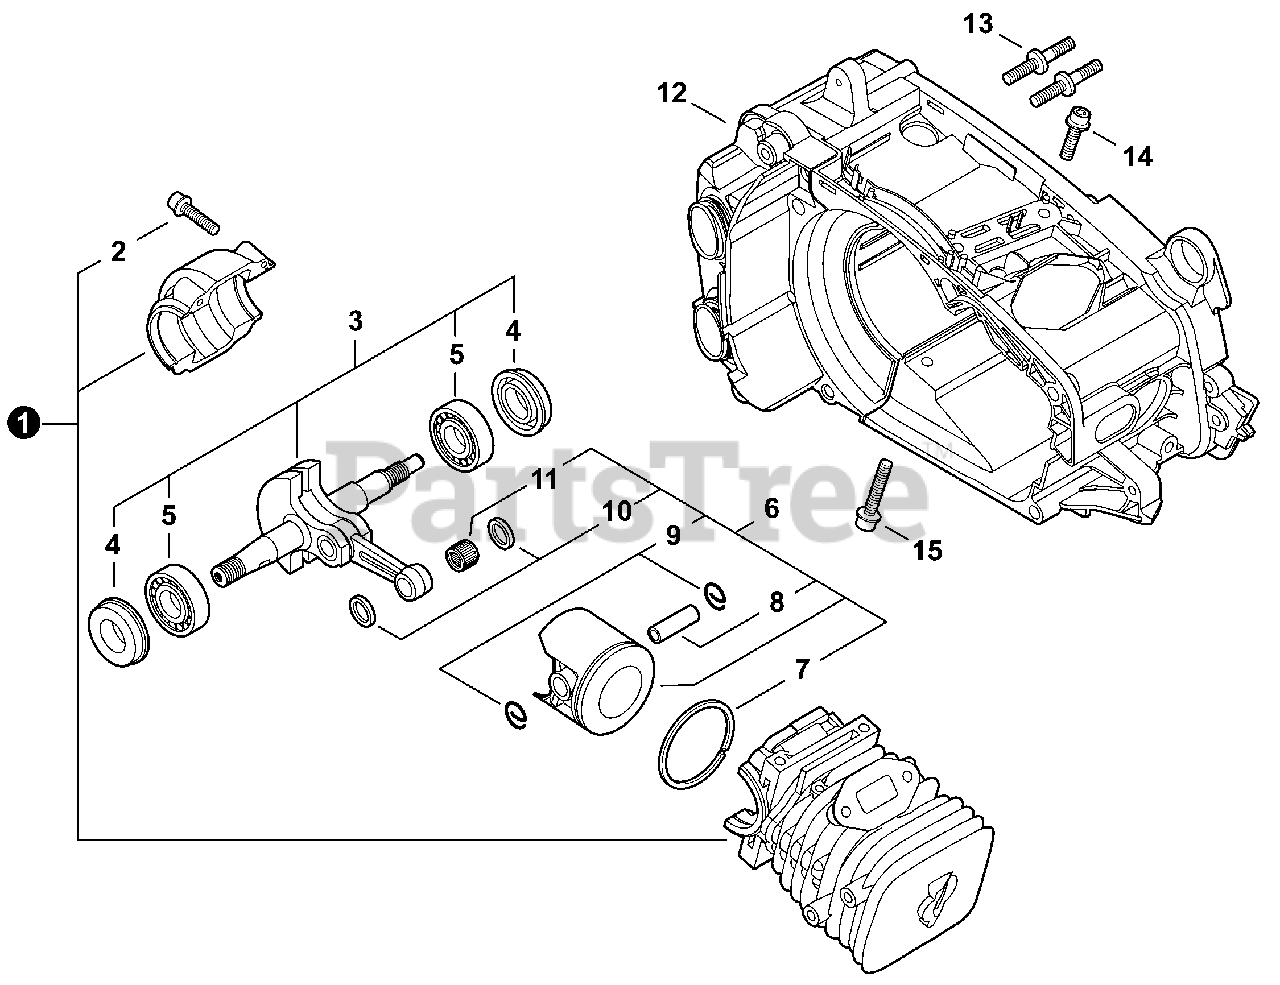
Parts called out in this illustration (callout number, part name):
1	CRANKCASE SET
2	BOLT, TORX 5×20
3	CRANKSHAFT ASSY
4	SEAL, OIL 12
5	BEARING, BALL 6201
6	PISTON KIT
7	RING, PISTON
8	PIN, PISTON 5.5×8×29
9	RING, SNAP
10	WASHER, THRUST
11	BEARING, NEEDLE 8
12	COVER, ENGINE
13	STUD, GUIDE BAR
14	BOLT, TORX 5×20
15	BOLT, TORX 5×30
